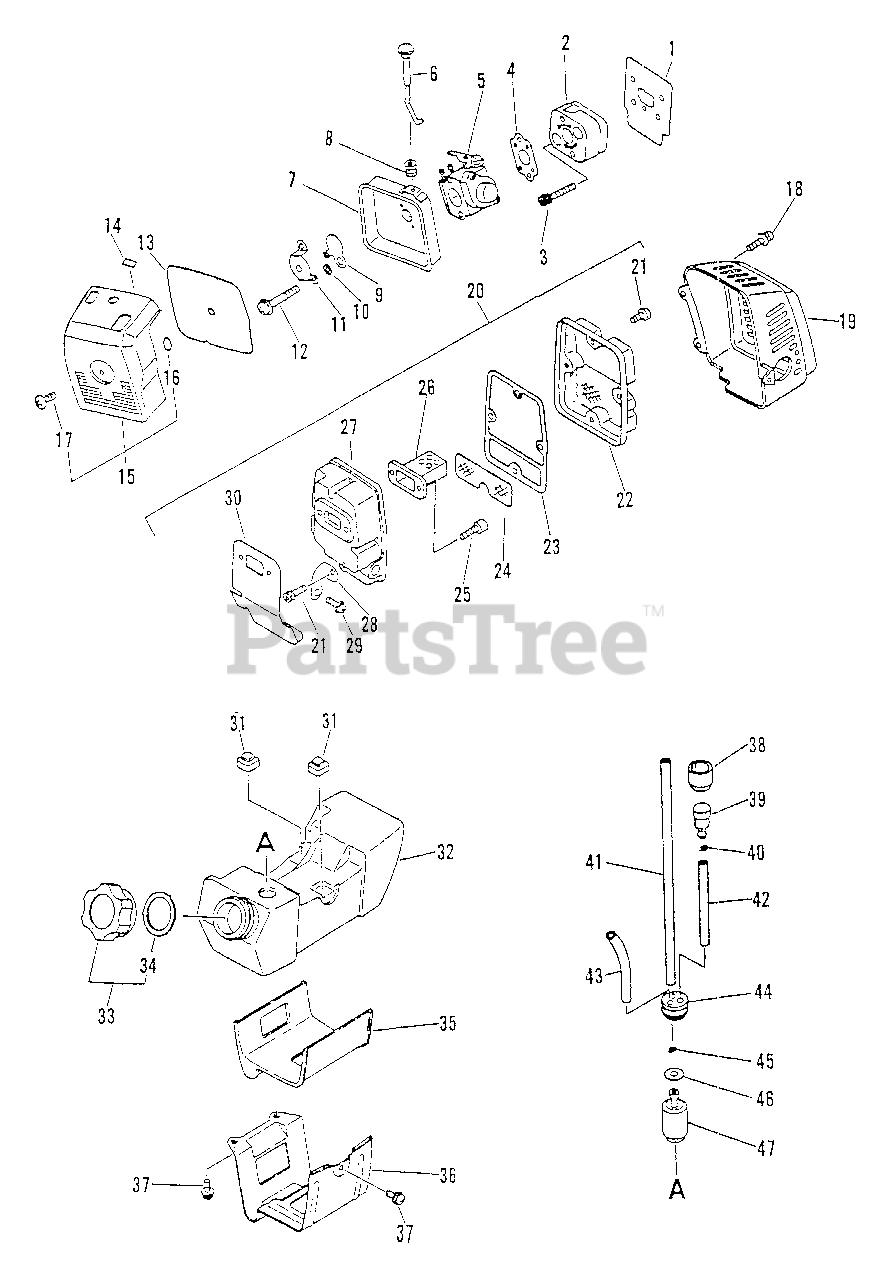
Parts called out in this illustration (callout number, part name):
1	GASKET, INTAKE
2	INSULATOR
3	SCREW - 5X25
4	GASKET, INTAKE
5	CARBURETOR C1U-K21A
6	ROD, CHOKE
7	CASE, AIR FILTER
9	SHUTTER, CHOKE
10	WASHER - 5
11	PLATE, PREVENT
12	SCREW - 5X45
13	FILTER, AIR
13	FILTER, AIR - HEAVY DUTY
14	LABEL - CHOKE
15	AIR FILTER COVER ASSY
16	O-RING - 3
17	THUMBSCREW
18	SCREW - 4X8
19	COVER, MUFFLER
20	MUFFLER ASSY
21	SCREW - 5X14
22	LID, MUFFLER
23	GASKET, EXHAUST
24	SCREEN, SPARK ARRESTOR
25	SCREW - 5X18
26	BAFFLE, MUFFLER
27	MUFFLER
28	BRACKET, MUFFLER
29	SCREW - 5X10
30	GASKET, EXHAUST
31	CUSHION, FUEL TANK
32	TANK, FUEL
33	CAP ASSY
34	GASKET, CAP
36	BRACKET, FUEL TANK
37	SCREW - 5X12
38	COVER, VENT
39	VENT, FUEL TANK
40	CLIP - 6
41	PIPE - 3X5X180 -- BLACK
42	PIPE - 3X6X70 -- BLACK
43	PIPE - 3X6X90 -- CLEAR
44	GROMMET
45	CLIP - 5.5
46	WASHER - 5
47	FILTER, FUEL
